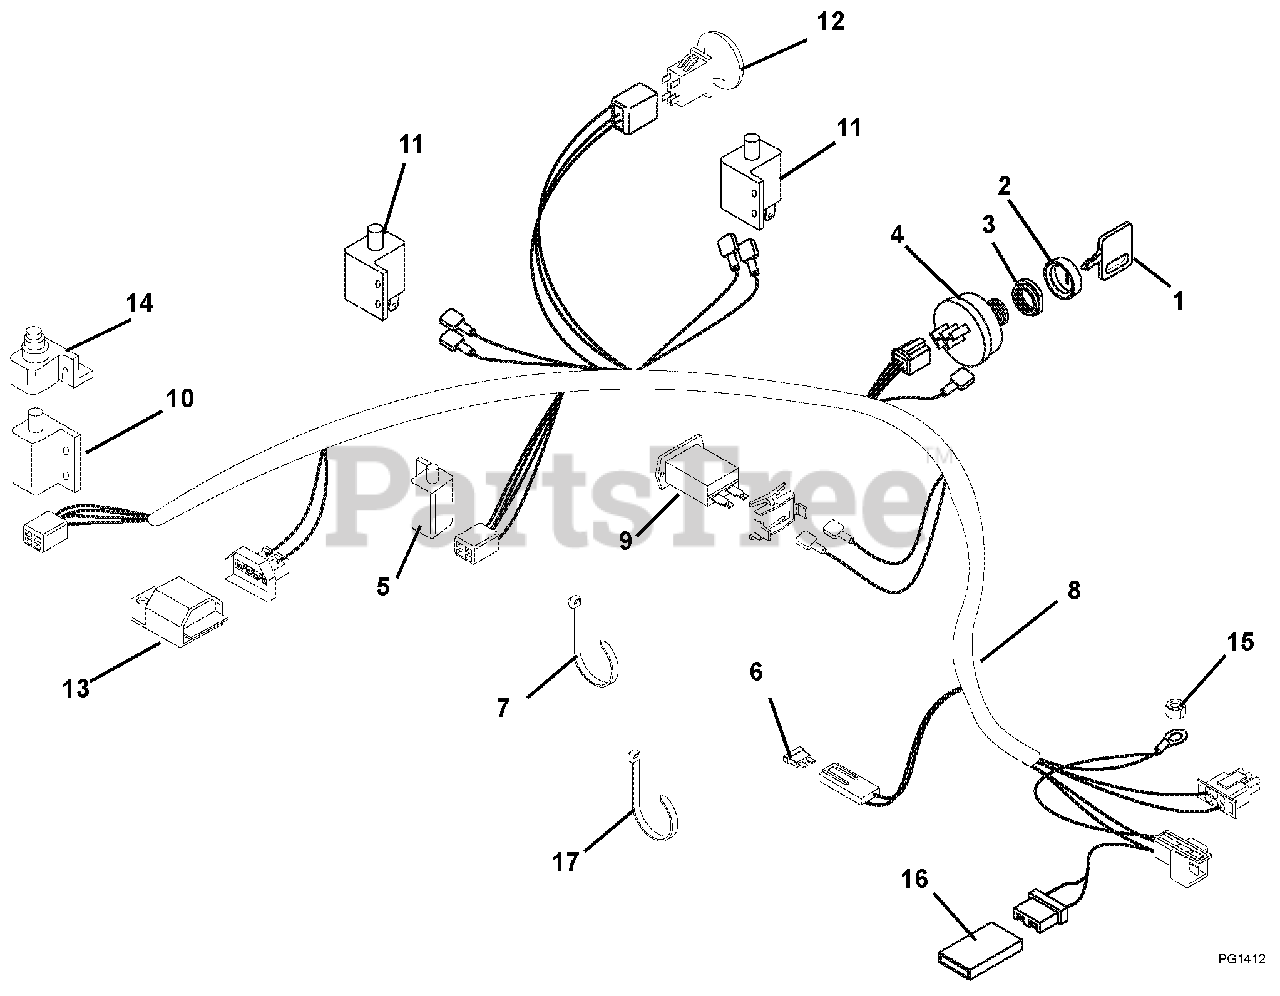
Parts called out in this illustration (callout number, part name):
1	Key, with Cap
2	Cap, Ignition Switch
3	Nut, Panel .562-24
4	Key Switch
5	Switch, Double Pole N.O./N.O.
6	Fuse, 25 Amp
7	Tie Wrap-Black
8	Wire Harness
9	Hour Meter-Quartz
10	Switch, Interlock
11	Switch, Single Pole (N.O.)
12	Switch, Clutch With Retainer
13	Module, Interlock, Recoil
14	Boot, Rubber
15	Nut, Locking-Top-Flange .31-18
16	Diode, Connector Shell
17	Tie Wrap
